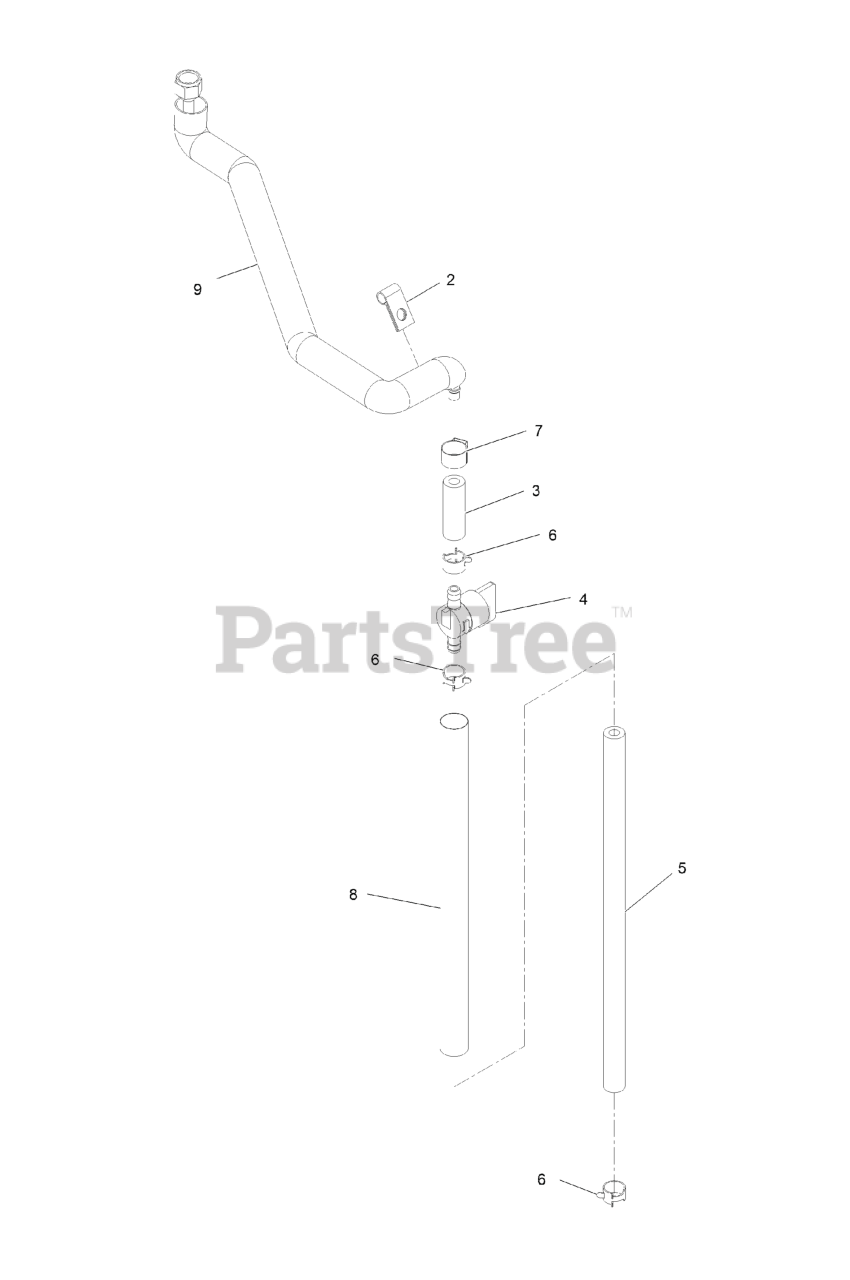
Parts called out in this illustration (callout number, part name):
2	CLIP-CLOSED, INSULATED
3	Hose-Fuel
4	VALVE-FUEL
5	HOSE-FUEL
6	CLAMP-HOSE
7	Clamp-Hose, Fuel
8	Sleeve, Thermal
9	SLEEVE-THERMAL,
